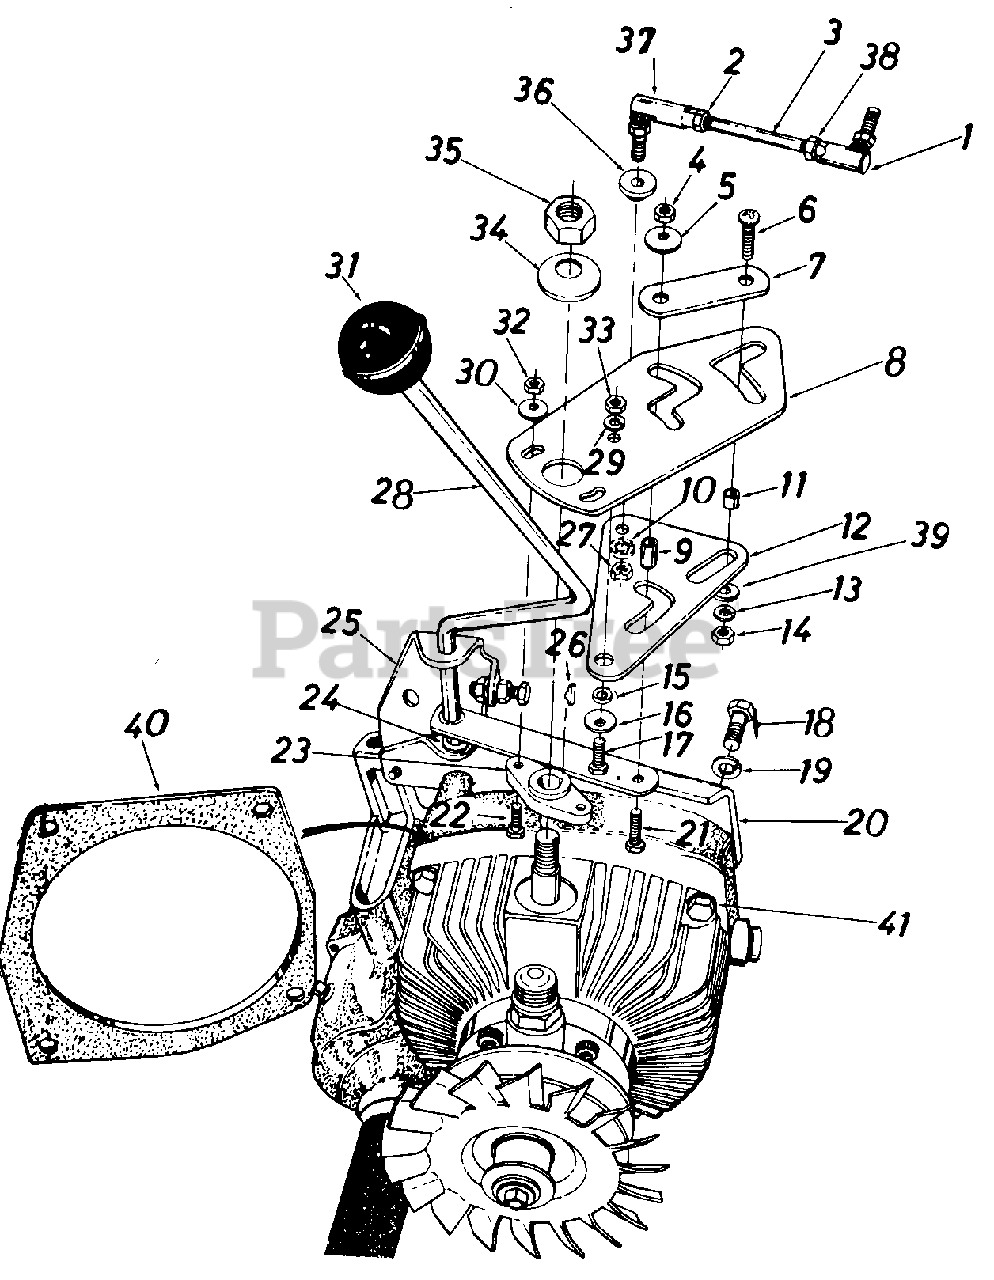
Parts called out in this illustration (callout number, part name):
1	Ball Joint Ass'y. 3/8-24 Thd.
2	Hex Nut 3/8-24 Thd. (L.H. Threads)
3	Control Rod 3/8-24 x 3.75" Lg.
4	Hex Top L-Nut 3/8-24 Thd.
5	Fl-Wash. .385" I.D. x .87" O.D.
6	Truss Mach. Scr. Phil. 5/16-18 x 1.00" Lg.
7	Locking Link
8	Pintle Main Control Plate
9	Spacer.377" I.D. x .500" O.D. x .830" Lg.
10	L-Wash. 3/8" I.D.*
11	Spacer.315" I.D. x .500" O.D. x .350
12	Pintle Drive Plate
13	L-Wash. 5/16" I.D.*
14	Hex Nut 5/16-18 Thd. *
15	Spacer .38" I.D. x .625"
16	Bell-Wash. .39" I.D. x 1.13" O.D.
17	Hex Bolt 3/8-24 x 1.00" Lg.
18	Hex Bolt 3/8-16 x 1.0" Lg. (Grade 5)
19	L-Wash. 3/8" I.D.*
20	Shift Lever Bracket
21	Hex Bolt 318-24 x 1.25" Lg.
22	Hex Bolt 1/4-28 x .75" Lg.*
23	Pintle Hub
24	Nyliner.375" Dia. x .140
25	Shift Lever Bracket-Upper
26	#5 Hi-Pro Key 1/8 x 5/8 Dia.
27	Hex Top L-Nut 3/8-24 Thd.
28	Shift Lever Ass'y.
29	L-Wash. 3/8" I.D.
30	Fl-Wash. .385" I.D. x .87" O.D.
31	Gear Shift Knob
32	Hex Nut 1/4-28 Thd.
33	Hex Top L-Nut 3/8-24 Thd.
34	Bell-Wash. .505" I.D. x 1.00" O.D.
35	Hex Nut 1/2-13 Thd.
36	Shld. Spacer.625" I.D.
37	Ball Joint Ass'y. 3/8-24 L.H.
38	Hex Jam Nut 3/8-24 Thd.
39	Fl-Wash. .33" I.D. x 1.25"
40	Gasket
41	Hex Bolt 2.75" Lg.
